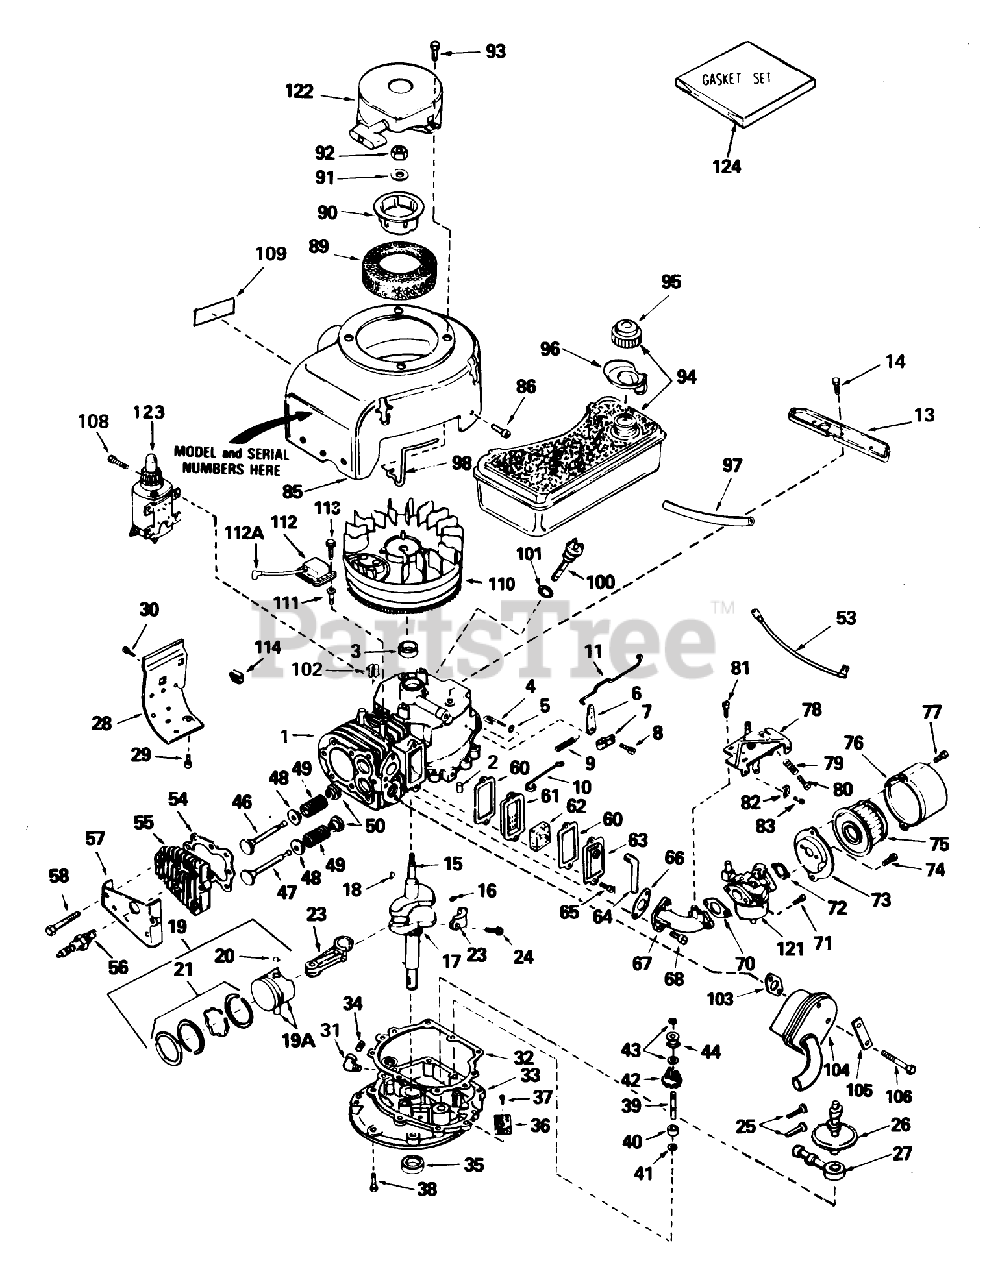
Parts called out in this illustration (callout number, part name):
1	Cylinder Assy., (Incl. Ref. #2, 3, 100 101)
2	Pin-Dowel
3	Oil Seal
4	Rod, Governor (Incl. Nos. 146)
5	Washer-Flat
6	Lever-Governor
7	Clamp-Lever, Governor
8	Screw
9	Spring Governor
10	Link Governor Spring
11	Link Governor
13	Bracket-Blower Housing
14	Screw (1/4-20x19/32)
15	Crankshaft Assy. (Incl. Ref. #16 17)
16	Pin, Groove
17	Gear-Crankshaft
18	Key-Flywheel
19	Piston, Pin Ring Assy. (Std.) (Incl. Ref. #19A, 20 21)
19	Piston, Pin Ring Assy. (.010 oversize) (Incl. Ref. #19A, 20 21 )
19	Piston, Pin Ring Assy. (.020 oversize) (Incl. Ref. #19A, 20 21)
19A	Piston Pin Assy. (Std.) (Incl. Ref. #20)
19A	Piston Pin Assy. (.010 oversize) (Incl. Ref. #20)
19A	Piston Pin Assy-. (.020 oversize) (Incl. Ref. #20)
21	ORing
21	Ring Set (.010" OS)
21	Ring Set (.020" OS)
23	Rod Assy., Connecting (Incl. Nos. 10 18)
24	Bolt, Connecting Rod
25	Lifter-Valve
26	Screw
27	Pump, Oil
28	Extension-Blower Hsng.
29	Screw
30	Screw
31	Elbow, 90? Street, 1/4-18 thread (Can be purchased locally)
32	Gasket-Cover, Cylinder
33	Flange Assy., Mounting (Incl. Ref. #34 thru 37 39)
34	Plug-Drain, Oil (SQH 1/4-18)
35	Seal-Oil
36	Screen-Oil Filter
37	Screw
38	Screw (1/4-20 x 1-1/4)
39	Shaft, Governor
40	Spacer Assy. Governor (Incl. Ref. #41)
41	Washer-Flat
42	Governor Gear ASM
43	Ring-Retaining
44	Spool-Governor
46	Valve, Intake (Standard)(Incl. No. 9)
46	Valve, Intake (1/32" oversize)(Incl. No. 9)
47	Valve, Exhaust (Standard)(Incl. No. 9)
47	Valve, Exhaust (1/32" oversize)(Incl. No. 9)
48	Cap-Spring, Valve
49	Spring-Valve
50	Keeper-Spring, Valve
53	Wire-Ground
54	Gasket-Cylinder Head
55	CYLINDER HEAD
56	Plug, Spark (J17LM or equiv.)
56	Plug, Spark (Champion RCJ-8)
57	Cover-Head, Cylinder
58	Screw (5/16-18 X 2-1/2)
60	Gasket-Breather
61	Body-Breather
62	Element-Breather
63	Cover-Valve
64	Tube-Breather
65	Screw
66	Gasket-Intake
67	Pipe-Intake
68	Screw (T-30, 5/16-18x1-3/32)
70	Gasket
71	Screw-Hex Hd.
72	Gasket
73	Bracket
74	Screw (10-32 x 1/2)
75	Element
76	Body-Air Cleaner
77	Screw
78	Control Assy.Speed (Incl. Ref. #79 80)
79	Spring-Compression
80	Screw
81	Screw (10-24 x 9/16)
82	Conduit
83	Screw (10-32 x 3/8)
85	Housing-Blower
86	Screw
89	Screen-Starter
90	Cup-Starter
91	Washer-Belleville
93	Screw
94	Tank Assy., Fuel (Incl. No. 127)
95	Cap-Fuel
96	Deflector-Fuel
97	Line-Fuel (8.62)
98	Clamp, Tank Holdown
100	Dipstick, Oil (Incl. No. 45)
101	Gasket
102	Clip-Wire
103	Gasket Exhaust
104	Muffler
105	62513 SNWTHWR W/284
106	Screw Hex Hd.
108	Screw
109	Decal-Instruction
110	Flywheel
112	Solid State
112A	Cover-Spark Plug
113	Screw
114	Clip, Spring
121	Carburetor
122	tarter-Rewind
123	Tine Shaft
124	Gasket Set
